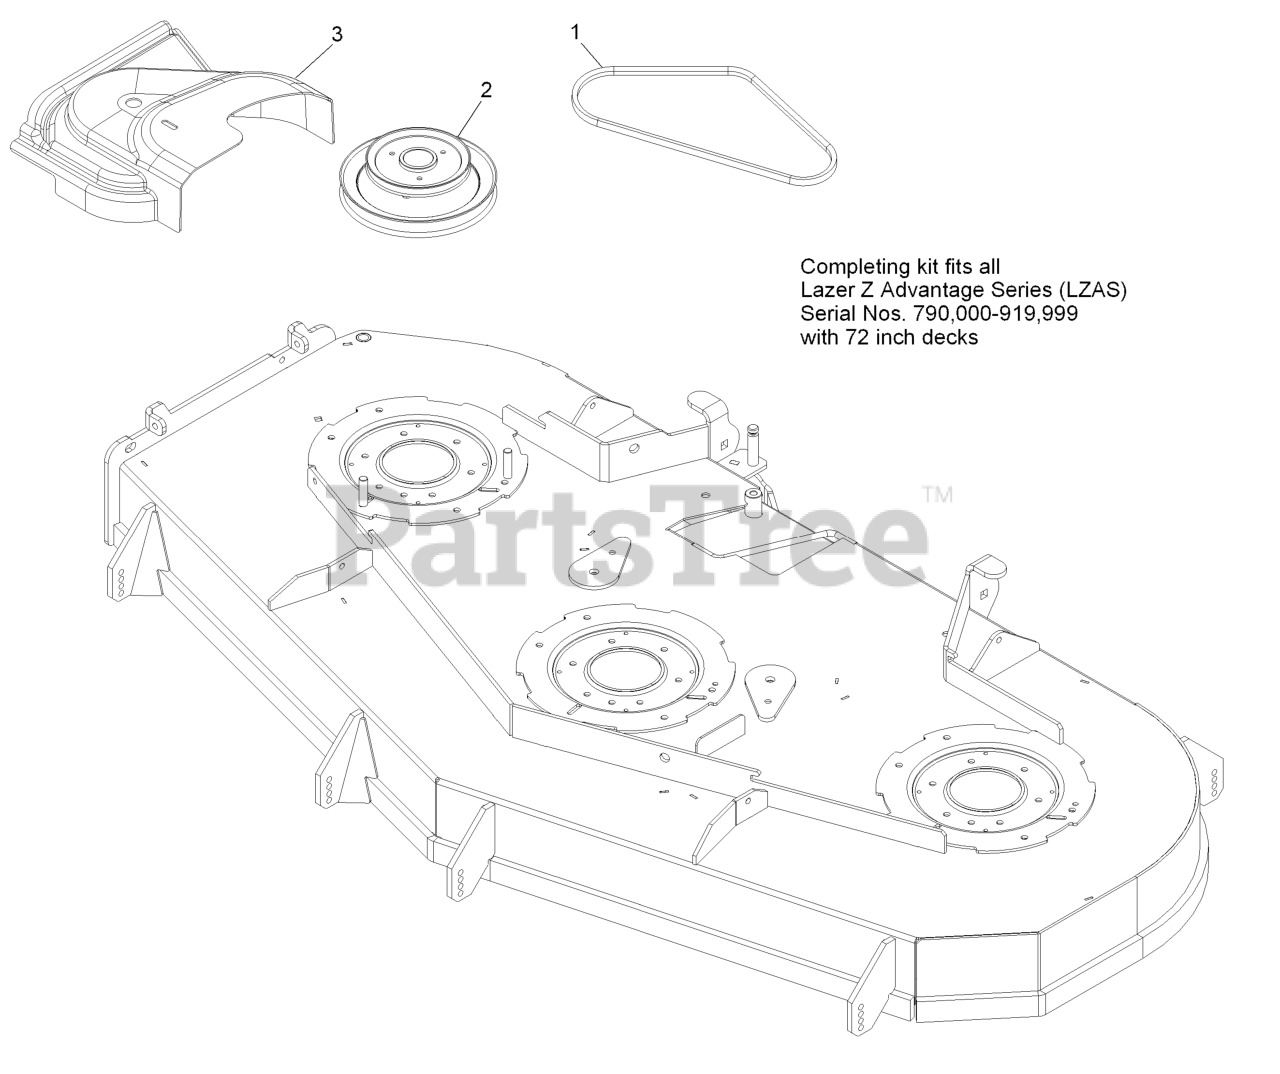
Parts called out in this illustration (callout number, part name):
1	Belt, Blower Drive 72
2	Jackshaft,Uv Drive 724
3	Cover,Belt Uv 72
